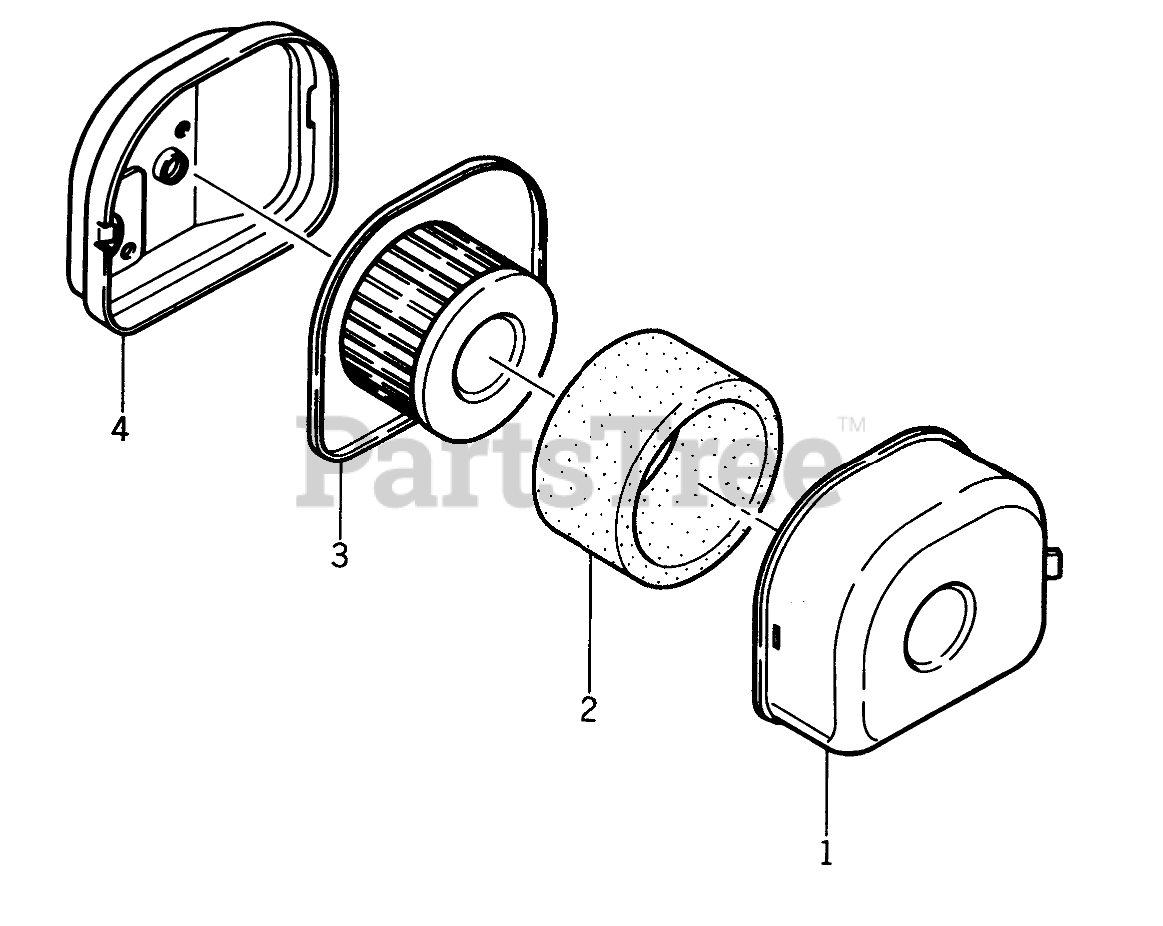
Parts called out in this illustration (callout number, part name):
1	Air Cleaner Cover
2	WRAPPER
3	ELEMENT-PAPER
4	CASE-AIR CLEANER
